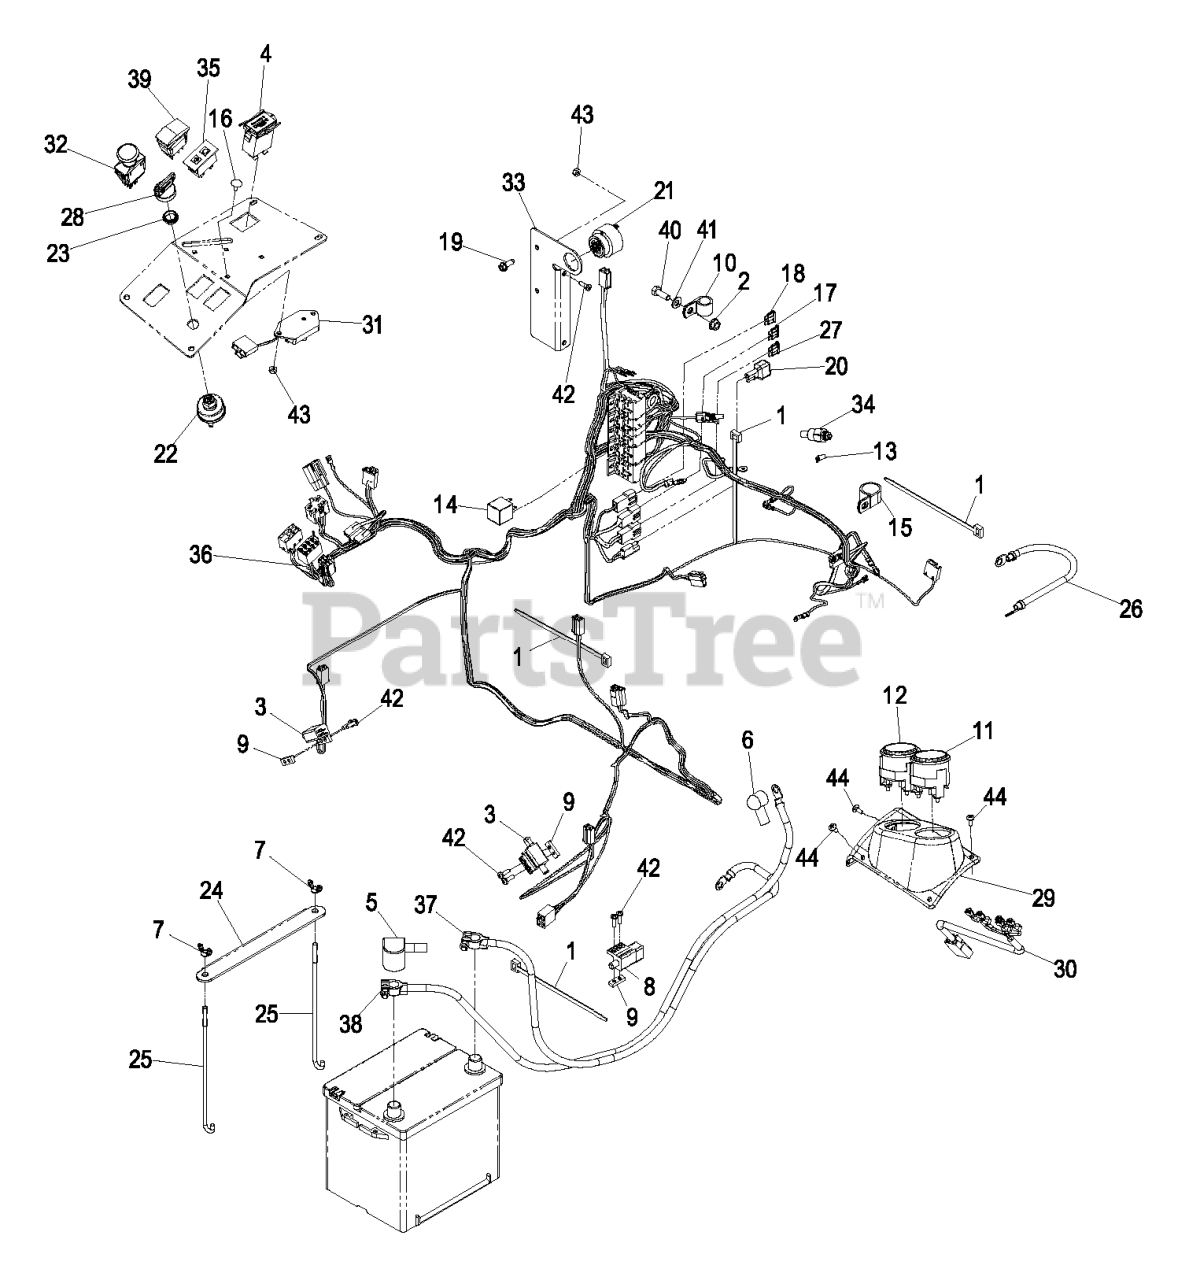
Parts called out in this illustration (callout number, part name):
1	TIE-PLASTIC
3	SWITCH-OPEN, NORMALLY
4	METER-HOUR
6	INSULATOR-SOLENOID
7	WINGNUT
9	PLATE-TAPPED
10	CLIP-LOOM
11	GAUGE-TEMPERATURE
12	GAUGE-VOLTMETER
15	CLIP-LOOM
16	BOLT-CARR
17	FUSE-BLADE TYPE, 20 AMP
18	FUSE-BLADE TYPE, 30 AMP
19	SCREW-HWHTF
21	ALARM-TONE, DUAL
23	NUT-SWITCH, IGNITION
24	HOLDDOWN-BATTERY
25	BOLT-HOLDDOWN
26	CABLE-ENGINE NEGATIVE
27	FUSE-40 AMP
28	KEY-IGNITION
29	BEZEL, GAGE XP LH TANK
30	ROD,LINKAGE BRAKE (PLATED
31	MODULE-DELAY, SEAT
32	SWITCH-PTO
33	ASM,RELAY BRKT W/ DECALS
34	SENDER,TEMPERATURE
35	LAMP-WARNING
36	HARNESS, WIRE KD902
37	CABLE-BATTERY NEGATIVE
38	CABLE-BATTERY POSITIVE
39	SWITCH-ROCKER
40	SCREW-HH
41	WASHER-PLAIN
42	SCREW-PPH
43	NUT-LOCK, NI
44	SCREW-PPH
